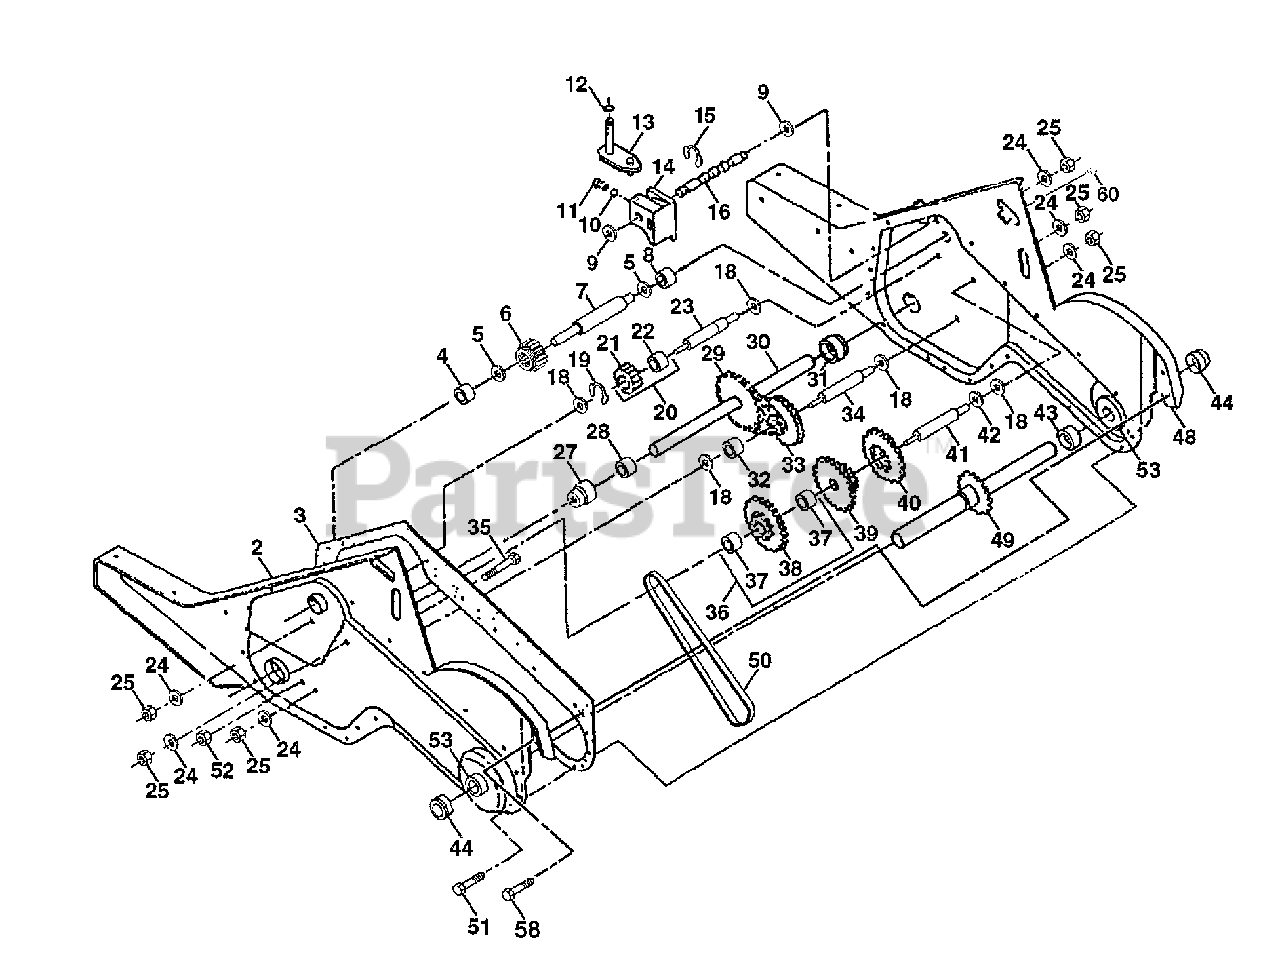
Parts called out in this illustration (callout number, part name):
1	Transmission Assembly
2	Gearcase, L.H. w/Bearing
3	Gasket, Gearcase
4	Bearing, Needle
5	Washer, Thrust 5/8 x 1.10 x 1/32
6	Pinion, Input
7	Shaft, Input
8	Bearing, Needle
9	Washer, Seal
10	Ball, Steel
11	Spring, Shift, Fork
12	O-Ring
13	Arm,. Shift
14	Fork, Shift
15	Ring, Klip
16	Shaft, Shift
18	Washer
19	Ring, Klip
20	Gear, Assembly, Reverse Idler
21	Gear, Reverse Idler
22	Bearing, Needle
23	Shaft, Reverse Idler
24	Washer, Lock 7/16
25	Nut, Hex 7/16-20
27	Bearing, Shaft, Ground Drive
28	Spacer 0.765 x 1.125 x 1.23
29	Chain #35-50 Pitch
30	Ground Shaft Assembly
31	Bearing, Shaft, Ground Drive
32	Spacer 0.70 x 1.00 x 1.150
33	Sprocket and Gear Assembly
34	Shaft, Reduction (2nd)
35	Screw, Whiz, Lock 5/16-18 x 3-1/2
36	Sprocket Assembly w/Bearing
37	Bearing, Needle
38	Sprocket, Tine
39	Gear, Cluster, Red 1st & 2nd
40	Gear, Reverse
41	Shaft, Reduction (1st)
42	Washer, Thrust
43	Spacer 1.01 x 1.75 x 0.760
44	Seal Asm, Oil
48	Gearcase, R.H. w/Bearing
49	Shaft, Tine
50	Chain, Roller #50-50 Pitch
51	Screw 1/4-20 x 1/2
52	Nut, Hex 5/16-18
53	Kit, Bearing, Tine Shaft
58	Bolt Shoulder 1/4-20 x 7/8
60	Fitting Grease
